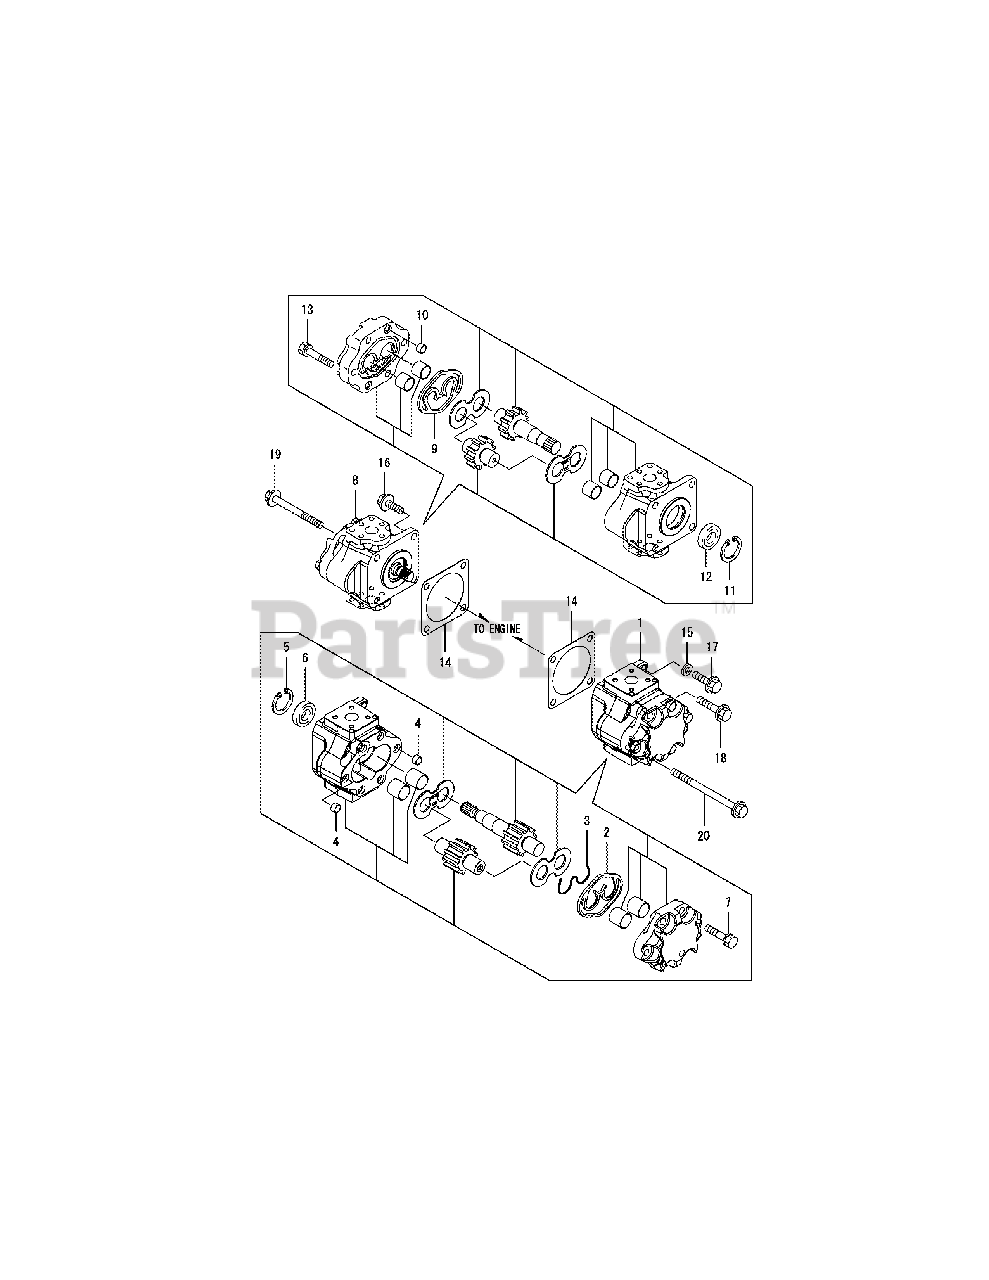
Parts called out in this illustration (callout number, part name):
1	HO-P(PW2-D-14A
6	SEAL TC15 32 07, OIL
8	HO-P(PW1-C-10C
12	SEAL TC15 32 07, OIL
15	SEAL WASHER 8S
16	BOLT M 8X 25 PLATED
17	BOLT M 8X 30 PLATED
18	BOLT M 8X 40 PLATED
19	BOLT M 8X 80 PLATED
20	BOLT M 8X115 PLATED
